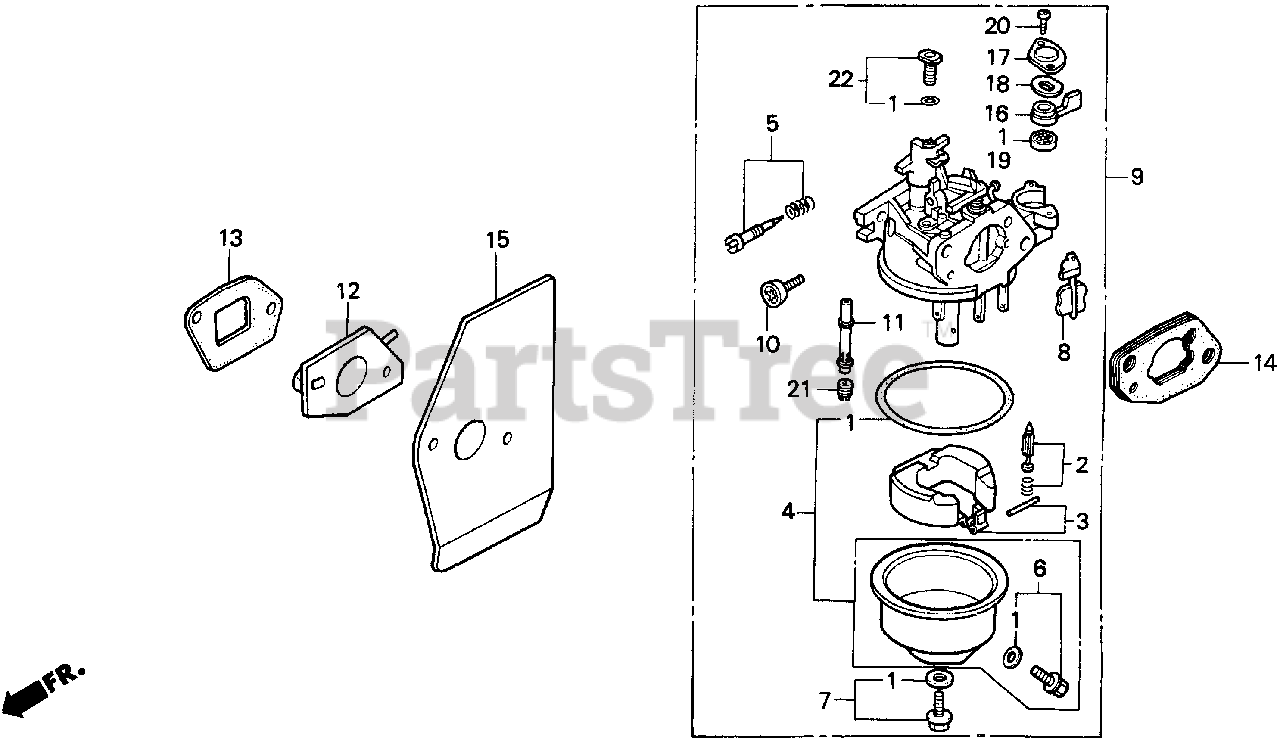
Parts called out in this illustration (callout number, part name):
1	GASKET SET
2	VALVE SET, FLOAT (SEAT NOT INCLUDED)
4	CHAMBER SET, FLOAT
5	SCREW SET, PILOT
6	SCREW SET, DRAIN
7	SCREW SET
8	CHOKE SET
9	CARBURETOR ASSY. (BE40A B)
9	CARBURETOR ASSY. (BE40A E)
9	CARBURETOR ASSY. (BE40A G/H)
10	SCREW, THROTTLE STOP
11	NOZZLE, MAIN
12	INSULATOR, CARBURETOR
13	GASKET, INSULATOR
14	SPACER, CARBURETOR
15	GASKET, CARBURETOR
16	LEVER, VALVE
16	LEVER, PETCOCK
17	PLATE, LEVER SETTING
18	SPRING, PETCOCK LEVER
19	GASKET, PETCOCK
20	SCREW, PAN (3X8)
21	JET, MAIN (#62)
21	JET, MAIN (#65)
21	JET, MAIN (#68)
21	JET, MAIN (#70)
22	JET SET, PILOT (#35)
22	JET SET, PILOT (#38)
